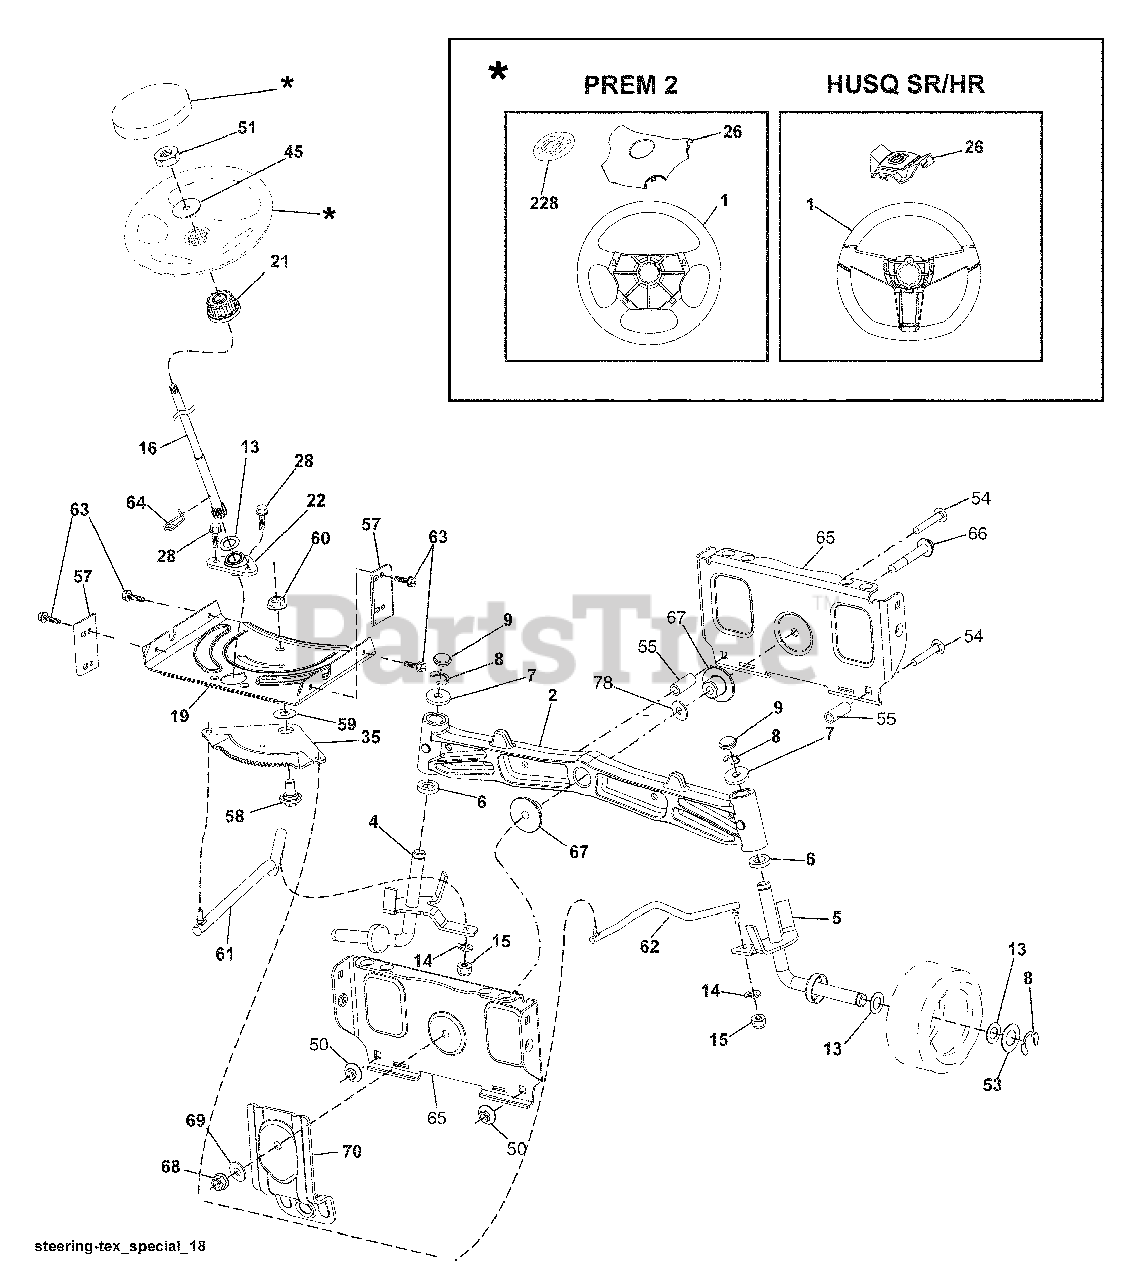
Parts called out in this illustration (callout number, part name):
1	Wheel, Steering
2	Axle Cast Iron
4	Spindle Asm., LH
5	Spindle Asm., RH
6	Washer, Thrust
7	Washer 25/32 x 1-5/8 x 16 Ga.
8	Ring, Klip #T5304-75
9	Cap, Spindle
13	Washer 25/32 x 1-1/4 x 16 Ga.
14	Washer, Lock Hvy Hlcl Spr 3/8
15	Nut, Crown Lock 3/8-24 unf
16	Shaft Steering
19	Plate Steering
21	Adapter, Wheel Steering
22	Bushing, Strg. Blk
26	Insert, Wheel Steering
28	Screw 3/8-16 x 3/4
35	Gear, Sector Plate
45	Washer 9/16 ID x 2-3/8 OD 12 Ga.
50	Nut Lock 3/8-16
51	Nut Hex Jam Toplock 1/2-20 unf
53	Washer Hardened .793 x 1.637 x .060
54	Bolt Hex 3/8-16 x 2-1/4
55	Spacer Brace Axle
57	Bracket Upstop
58	Bolt Shoulder Sector Pivot CFM
59	Washer Thrust Sector Steering
60	Nut Flange Lock 5/8-11
61	Draglink, LH
62	Draglink, RH
63	Screw 5/16-18 x 3/4
64	Retainer Clip Spring Steering
65	Brace Axle Front
66	Bolt Hex Fghd 7/16-14 x 3 Serr
67	Bushing PM Front Axle
68	Nut Lock Flange 7/16-14 Gr. 5
69	Washer 1.5 x .505 x .118
70	Bracket Deck Susp. Front
78	Washer Thrust
228	Decal, Wheel Steering
